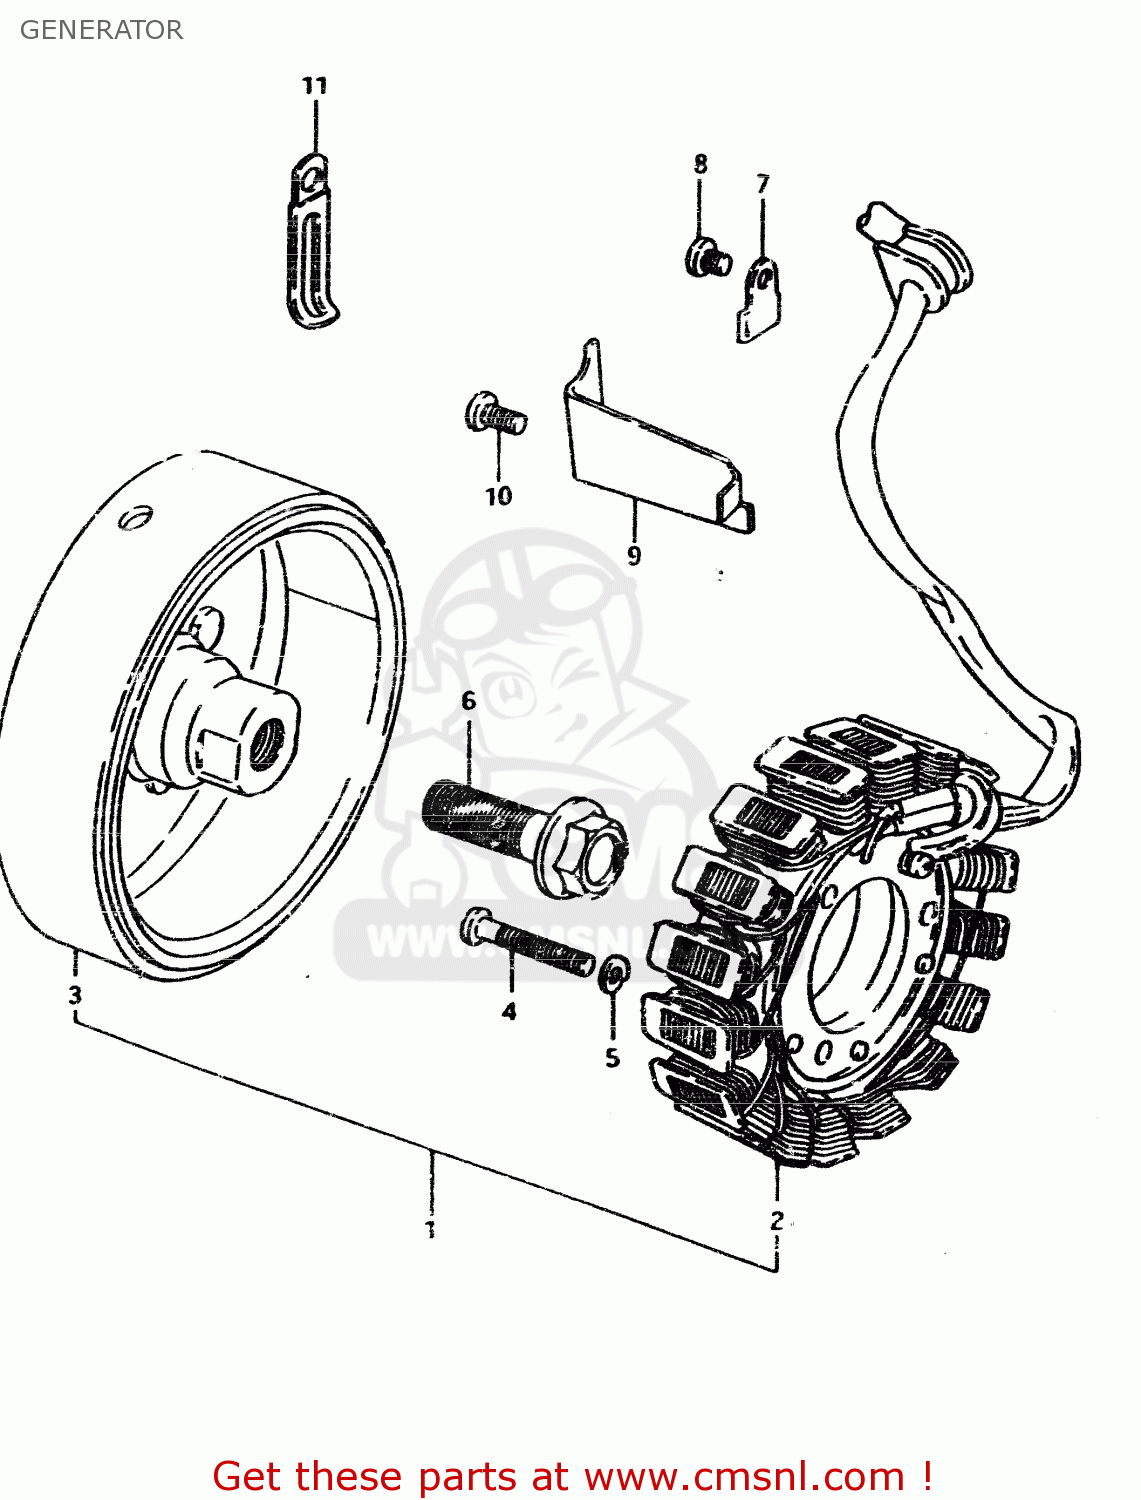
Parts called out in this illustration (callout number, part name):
1	GENERATOR ASSEMBLY
2	STATOR ASSEMBLY
3	ROTOR ASSEMBLY
4	SCREW
5	LOCK WASHER
6	BOLT(12X40)
7	CLAMP,GENERATOR LEAD WIRE
8	SCREW
9	CLAMP,GENERATOR LEAD WIRE
10	SCREW
11	CLAMP L:35
